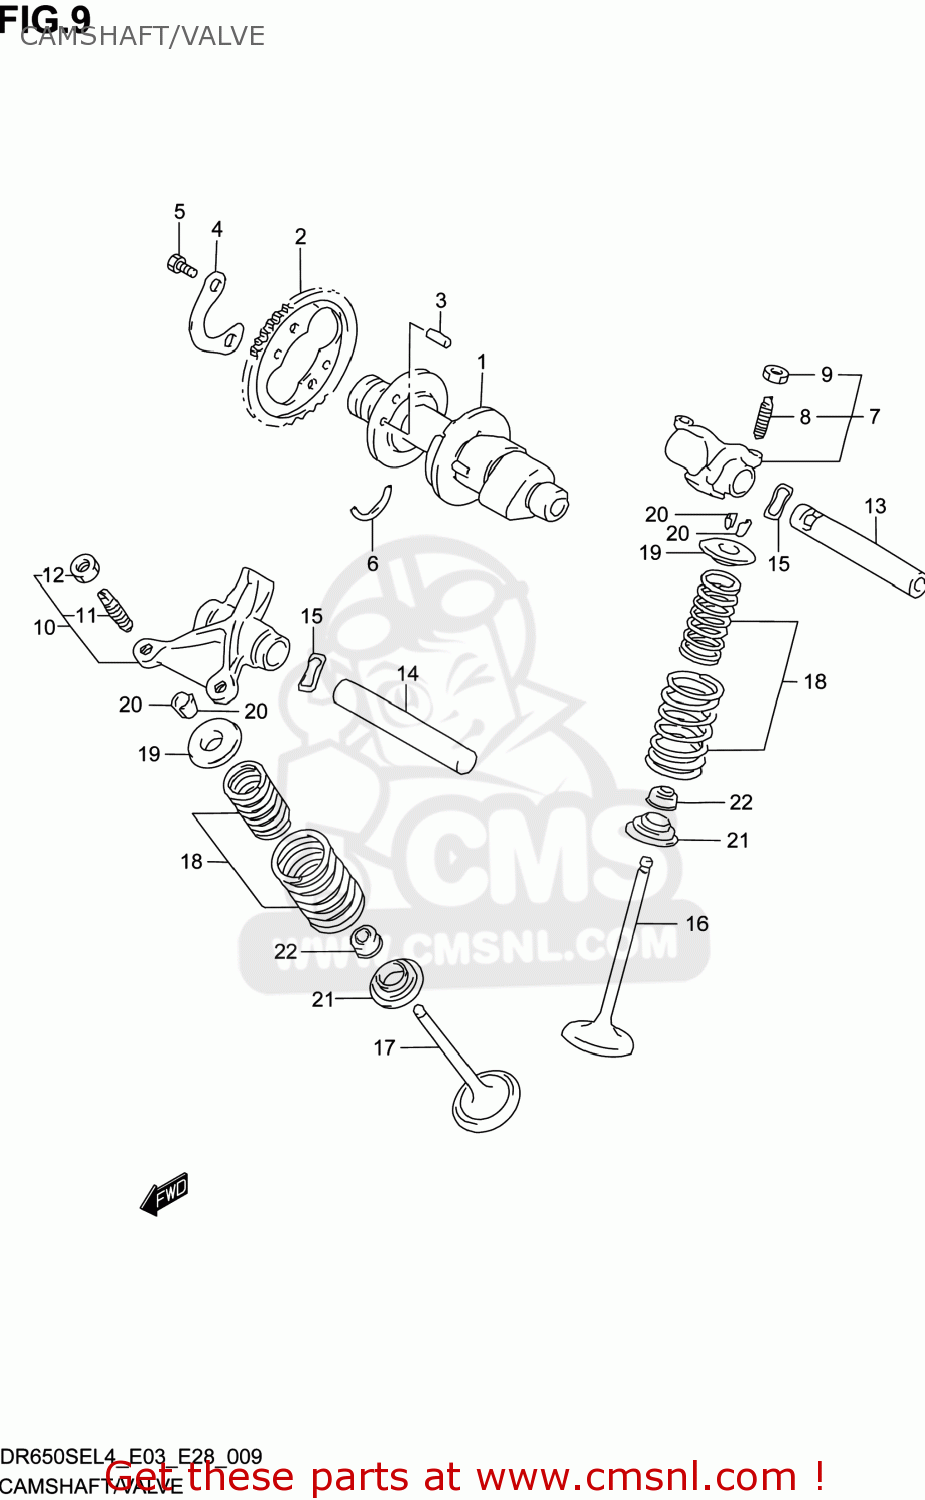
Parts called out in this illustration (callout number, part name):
1	CAMSHAFT
2	SPROCKET,CAMSHAFT(NT:38)
3	PIN(5X8)
4	WASHER,SPROCKET
5	BOLT(6X10.5)
6	C RING
7	ARM,VALVE ROCKER INTAKE
8	SCREW,TAPPET ADJUSTING
9	NUT,ADJUSTING SCREW
10	ARM,VALVE ROCKER EXHAUST
11	SCREW,TAPPET ADJUSTING
12	NUT,ADJUSTING SCREW
13	SHAFT,VALVE ROCKER ARM INTAKE
14	SHAFT,VALVE ROCKER ARM EXHAUST
15	WASHER
16	VALVE,INTAKE
17	VALVE,EXHAUST
18	SPRING SET,VALVE
19	RETAINER,VALVE SPRING
20	COTTER,VALVE
21	SEAT,VALVE SPRING
22	SEAL,OIL(5.5X11X8.2)
